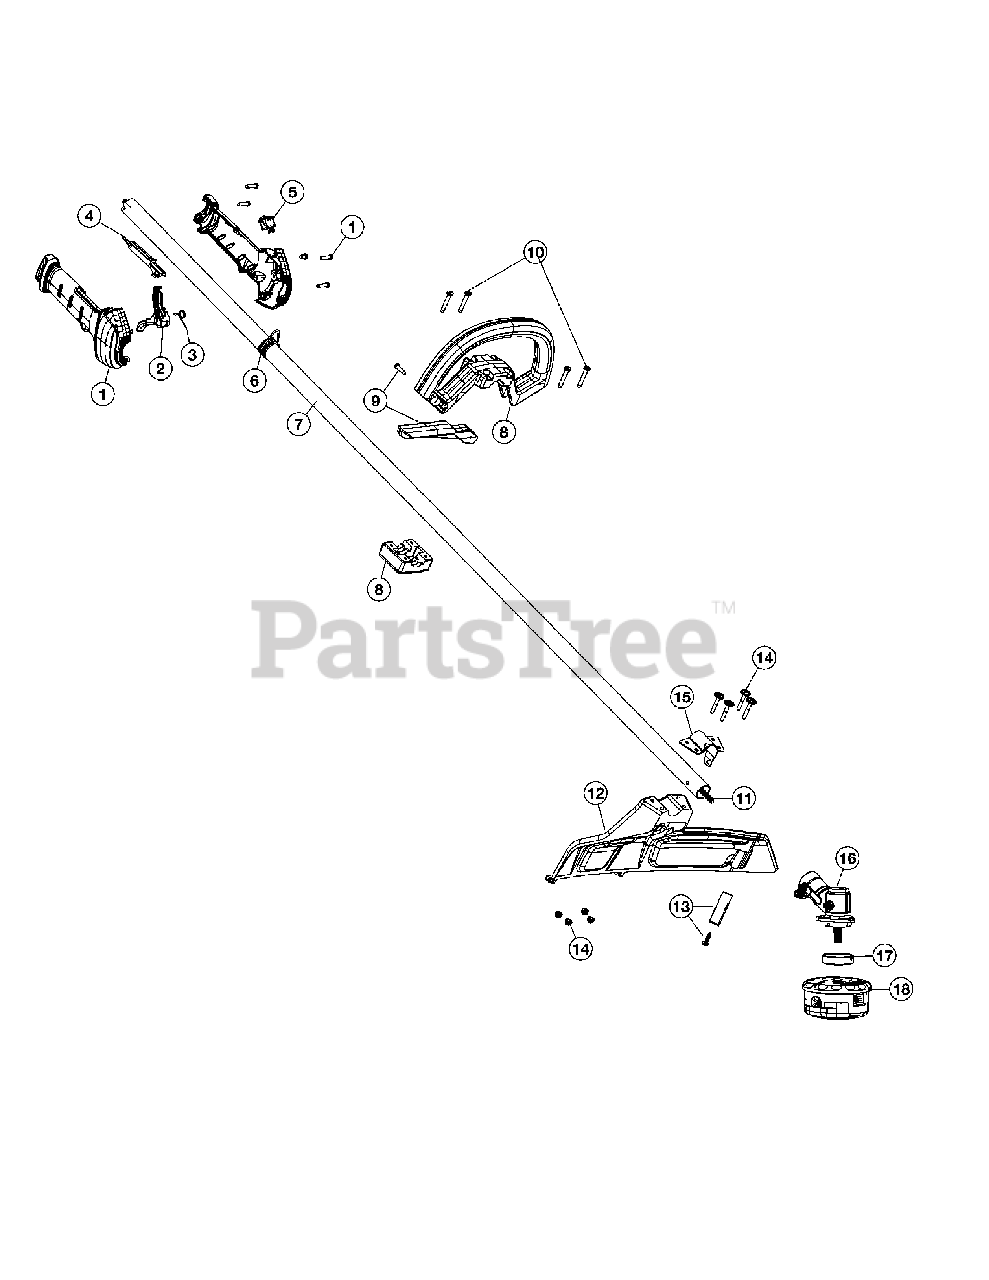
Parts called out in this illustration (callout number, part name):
1	Throttle Housing Assembly
2	Throttle Trigger
4	Throttle Lock-out
6	Shoulder Strap Clip
7	Driver Shaft Housing
8	D-Handle Assembly
9	Barrier Bar Assembly
11	Solid Drive Shaft
12	Shield Assembly
13	Blade Assembly
15	Guard Mounting Bracket
17	Gearbox Spacer
18	Cutting Head Assembly
